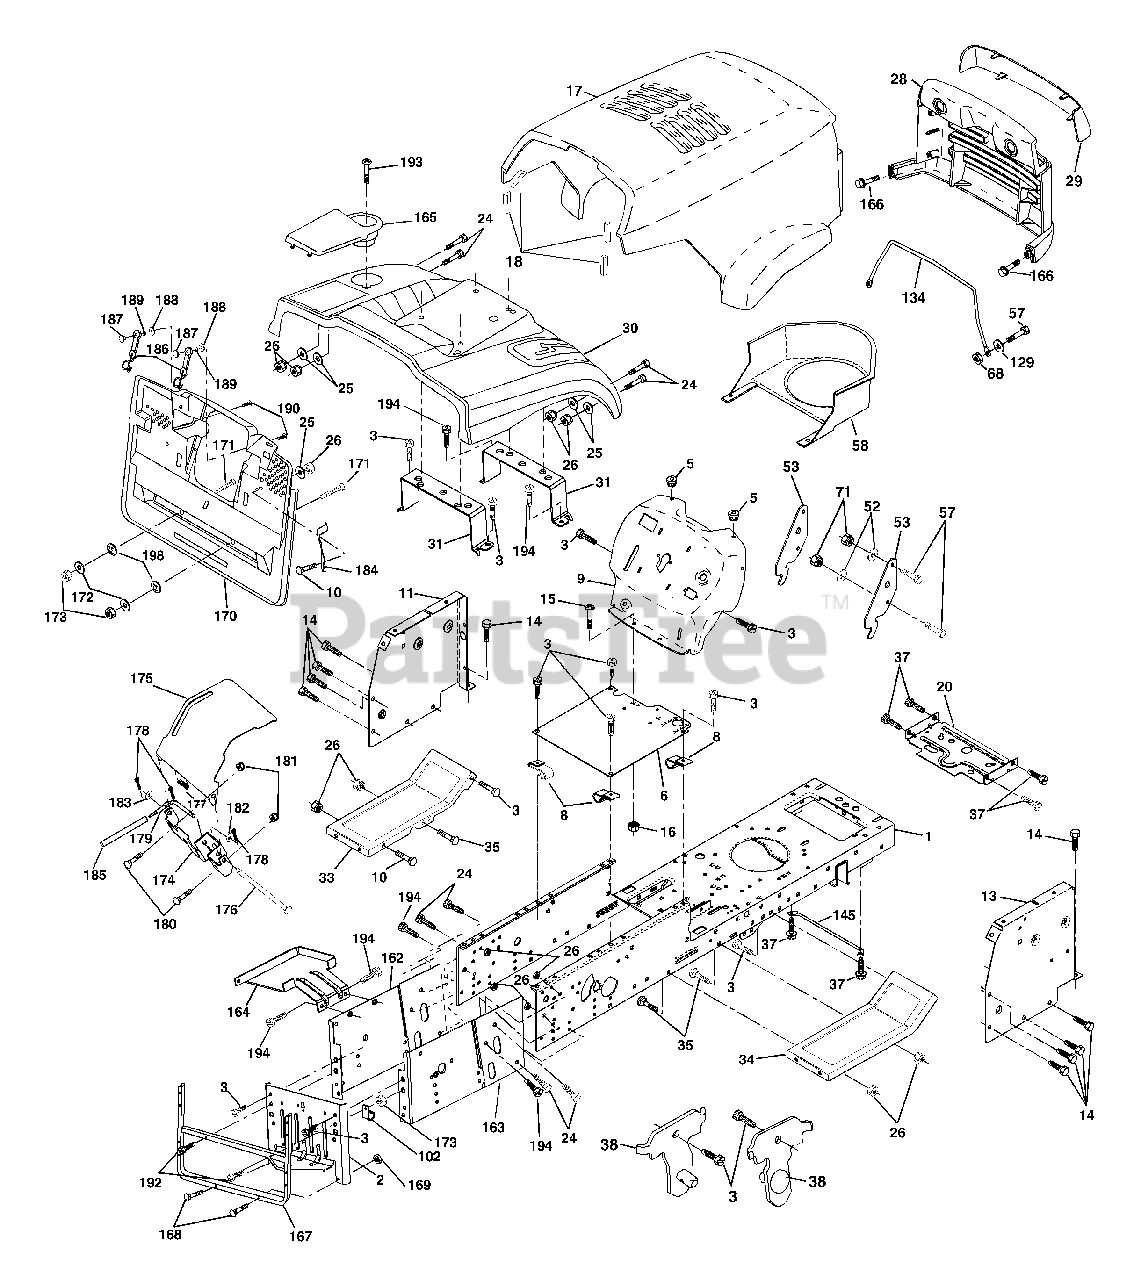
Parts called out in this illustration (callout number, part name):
1	Chassis Stamping
3	Screw 3/8-16 x 3/4
5	Bumper Hood/Dash
8	Clip Insulator 13/32 Mtg. Hole
10	Bolt, Carriage 3/8-16 x 3/4
11	Panel, Dash, L.H.
13	Panel, Asm. Dash R.H.
14	Screw Thdrol 3/8-16 x 1/2
15	Screw, Machine, Truss Head 5/16-18 UNC x 3/4
16	Nut
17	Hood Assembly
18	Bumper Hood
20	Plate Mtg. Battery/Fuel Tank
25	Washer 13/32 x 13/16 x 12 Gauge
26	Nut
28	Grille PL
29	Lens, Grille
31	Bracket, Fender Support
33	Footrest, L.H.
34	Footrest, R.H.
37	Screw Thdrol 5/16-18 x 1/2 TYT
38	Bracket Asm Pivot Mower Rear
52	Washer 9/32 x 7/8 x 16 Ga.
53	Bracket Pick off LT/Pl Husq
57	Bolt, Fin Hex 1/4-20 UNC x .75
58	Duct Air Engine Pl/Lt
68	Nut Keps Hex 1/4-20 Unc
71	Nut Crownlock 1/4-20 Unc
102	Clip Line Fuel 13-13/32 Mtg. Hole
129	Washer 9/32 x 5/8 x 16 Ga.
134	Rod Support Hood Husq P/L
145	Rod Pivot Chassis/Hood
162	Bracket Exten Chassis Lh CRD
163	Bracket Exten Chassis Rh CRD
164	Support Battery CRD
165	Cover Battery CRD Lt
166	Screw Hwhd Hi-Lo #13-16 x 3/4
167	Support Asm. Backplate WLDMNT
168	Bolt, RDHD SHT NK 1/4-20 x 1-1/2
169	Nut, Lock 1/4 LGE FLG Gr. 5 Zinc
170	Cover, Backplate Plastic Black
171	Bolt Rdhd Sqnk 3/8-16 x 2-1/2 G. 5
172	Washer 13/32 x 1-1/4 x 16 Ga.
173	Nut, Keps Hex 3/8-16 UNC
174	Bracket Switch FBI CRD
175	Guard Door Rear CRD
176	Pin Hinge Pivot
177	Spring Bagger Top LH Black
178	Pin Cotter 3/32 x 3/4 Cad Zinc
179	Rod Pivot FBI CRD
180	Bolt Hex HD 5/16-18 UNC x 1
181	Nut Crownlock 5/16-18
182	Washer .385 x .625 x 11 Ga.
183	Washer 13/32 x 13/16 x 16 Ga.
184	Bracket Actuator Bagger CRD
185	Tube Lever Switch FBI CRD
186	Latch Asm Mulch/Bagger
187	Nut Weld
188	Washer #10
189	Washer Lock #10
190	Washer Truss Head Phil 10-24 x 5/8
192	Screw Thdrol 3/8-16 x 1-1/4
193	Screw Truss 1/4-20 x 3/4 Tap/R
194	Screw 3/8-16 x .75
